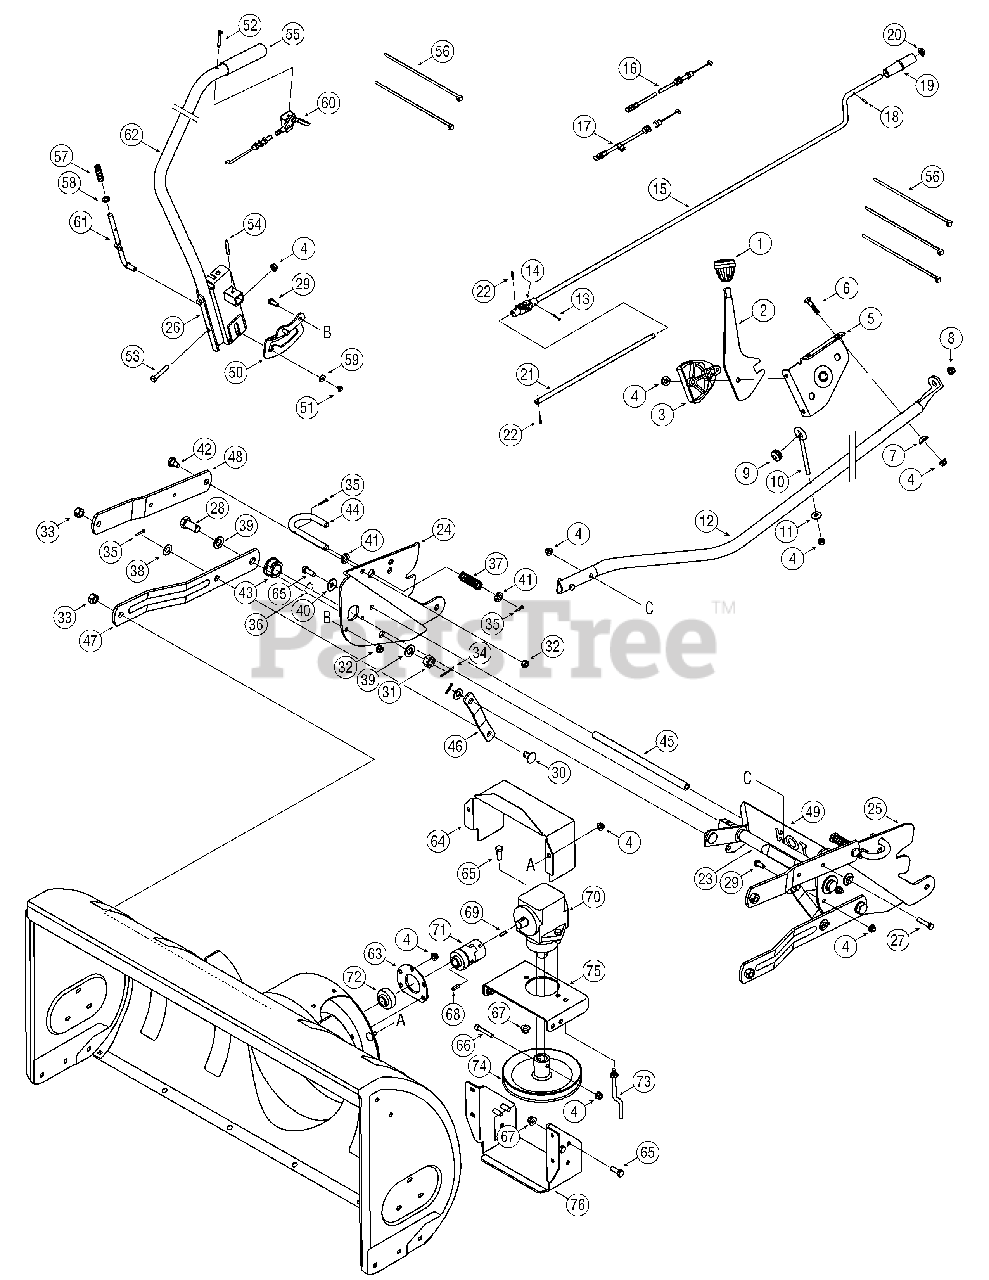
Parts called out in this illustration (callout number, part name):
1	Knob
3	Chute Tilt Cable Guide
4	Nylon Hex Lock Nut, 5/16-18
6	Carriage Bolt, 5/16-18 x 1.5
7	Saddle Washer, .32 x .93
8	Plastic Bushing
9	Rubber Grommet , .44 x .94 x5
10	Eye Bolt
11	Bell Washer, .340 x .872
13	Cotter Pin, 3/32 x .75
14	Joint Block Assembly
15	Chute Crank Rod, .375 x33
16	Chute Cable, 62"
17	Chute Cable w/ Clip, 62"
18	Rolled Pin, 1/8 x .63
19	Crank Knob
20	Push Cap, 3/8 ID
21	Rod, .375 x 11.375
22	Spirol Pin, .125 x .82
27	Hex Cap Screw, 5/16-18 x 1.50
28	Hex Cap Screw, 5/8-18 x 1.31
29	SCREW 5/16-18 x .75 GR5
30	Clevis Pin, .5 x .78
31	Slotted Hex Nut, 5/8-18
32	Hex Lock Nut, 3/8-16
33	Hex Lock Nut, 1/2-13
34	Cotter Pin, 1/8 x 1.25
35	Cotter Pin, .125 x .75
36	Snap Ring
37	COMPRESSION SPRING
38	FLAT WASHER .510X.
39	Flat Washer, .64 x 1.12 x .125
40	Bell Washer, .396 x 1.14 x .095
41	Flat Washer, .531 x .875 x .15
42	Shoulder Screw, .5 x .29, 3/8-16
43	Flange Bearing w/ Flats
44	Handle Rod
45	Rod, 1/2 x 11.55
47	Link, 15.4
49	Heat Shield
51	Hex Index Washer Screw #10-16
52	Pan Phillips Screw, #10-24 x .75
53	Hex Cap Screw, 5/16-18 x 1.75
54	Heavy Duty Spirol Pin, 1/4 x 1.5
55	Handle Grip
56	Cable Tie
57	Compression Spring
58	Flat Washer, .385 x .62 x .063
59	Flat Washer, .194 x .62 x .063
60	Lift Cable, 42" w/ Trigger Control
61	Lift Index Rod
63	Bearing Housing, 1.85 ID
65	Hex Cap Screw, 3/8-16 x 1.0
66	Socket Head Cap Screw
67	Flange Lock Nut, 3/8-16
68	Square Key, 3/16 x .75
69	Hi-pro Key, 3/16 x .75
70	Right Angle Drive
71	Coupling
72	Flange Ball Bearing, .75 x 1.85
73	Belt Keeper Rod
74	Drive Pulley, 7"
